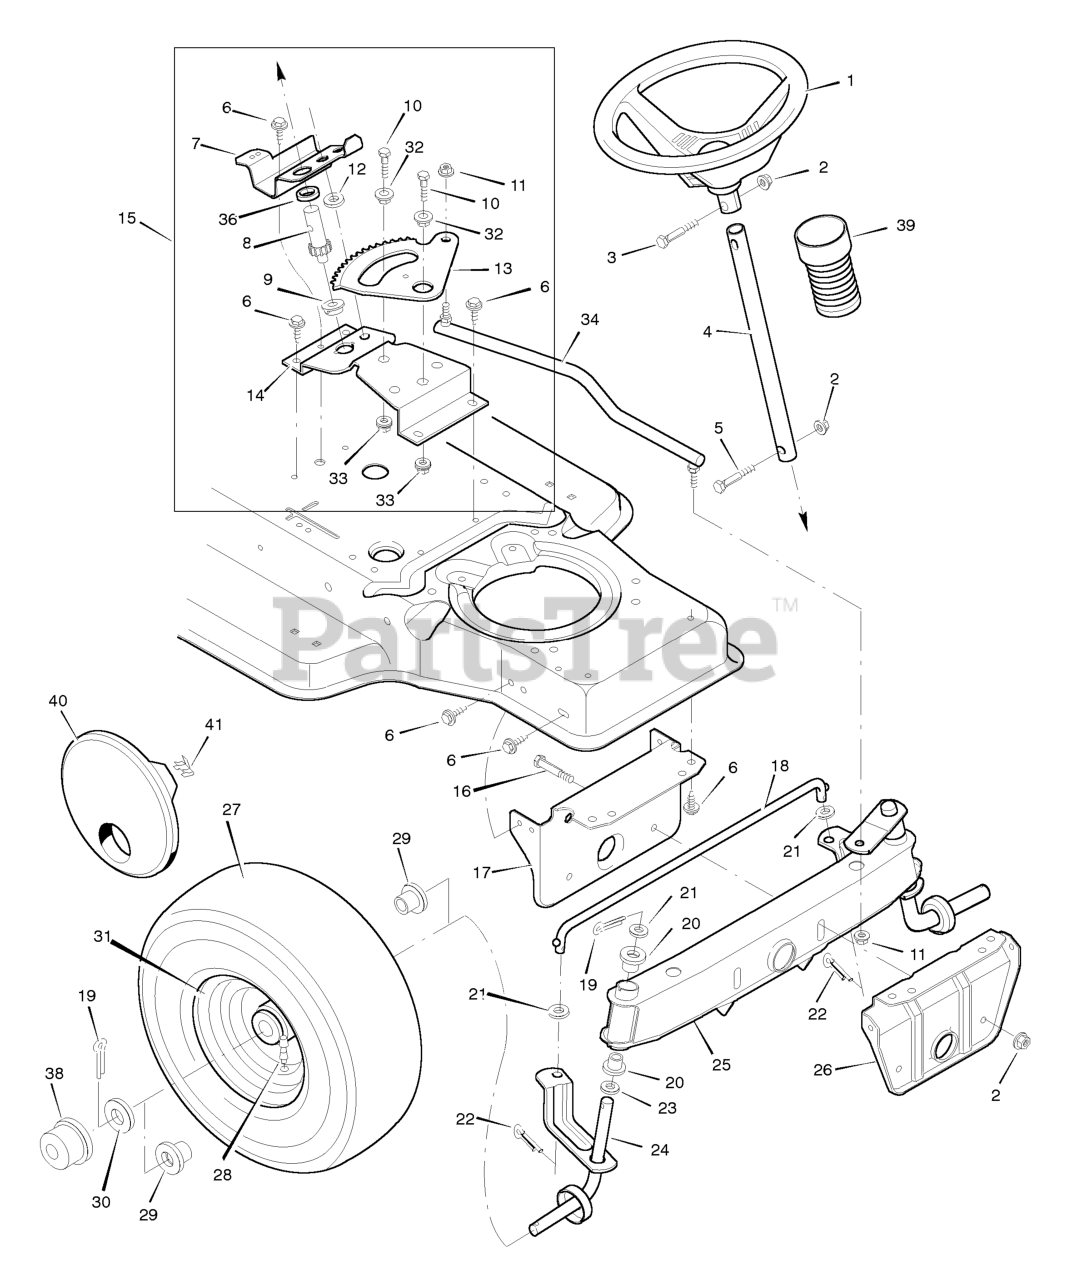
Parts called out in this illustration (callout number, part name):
1	Wheel, Steering
2	Nut, Hex
3	Bolt, Hex
4	Post, Steering
5	Bolt, Hex
7	Bracket, Sector
8	Gear, Pinion
9	Bearing
10	CAPSCREW, Hex Head, 5/16-18 x 1
11	Locknut, Flange
13	Gear, Sector
14	Bracket, Sector
15	Kit, Steering Gear
16	Bolt, Hex
17	Support, Rear Axle
18	Rod, Tie
19	Pin, Cotter
20	Bearing
22	Pin, Cotter
24	Spindle Assembly, Right
25	Spindle Assembly, Axle & Left
26	Support, Front Axle
27	Tire *
28	Stem, Valve
29	Bearing, Wheel
31	Wheel & Tire Assembly
32	Bearing
33	Locknut, Flange
34	Link, Drag
36	Spacer, Pinion Gear
38	Hub Cap
39	Bellows
40	Disc, Wheel
41	Clip, Retainer
